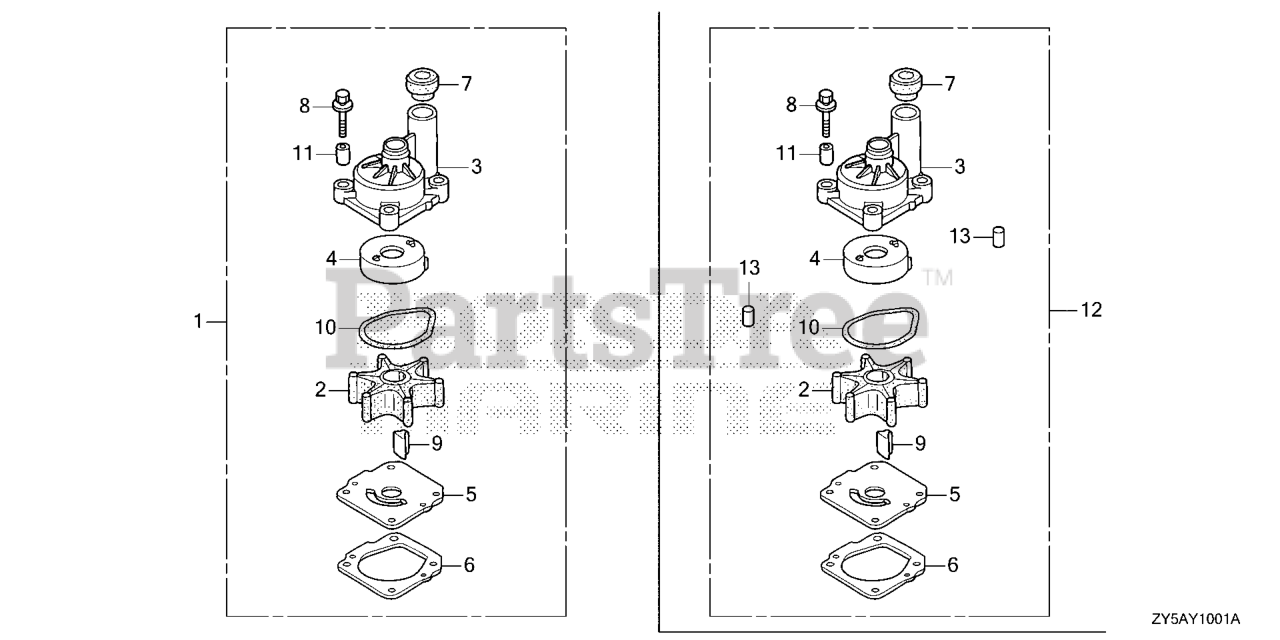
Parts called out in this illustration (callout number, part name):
1	PUMP KIT, IMPELLER
2	IMPELLER, PUMP
3	HOUSING, IMPELLER
4	LINER, PUMP
5	COVER, IMPELLER
6	GASKET B, IMPELLER
7	RING, WATER TUBE SEAL
8	BOLT-WASHER (8X40)
9	KEY, WOODRUFF
10	O-RING, WATER PUMP
11	COLLAR, DISTANCE
12	PUMP KIT, IMPELLER
13	PIN, DOWEL (6X10)
